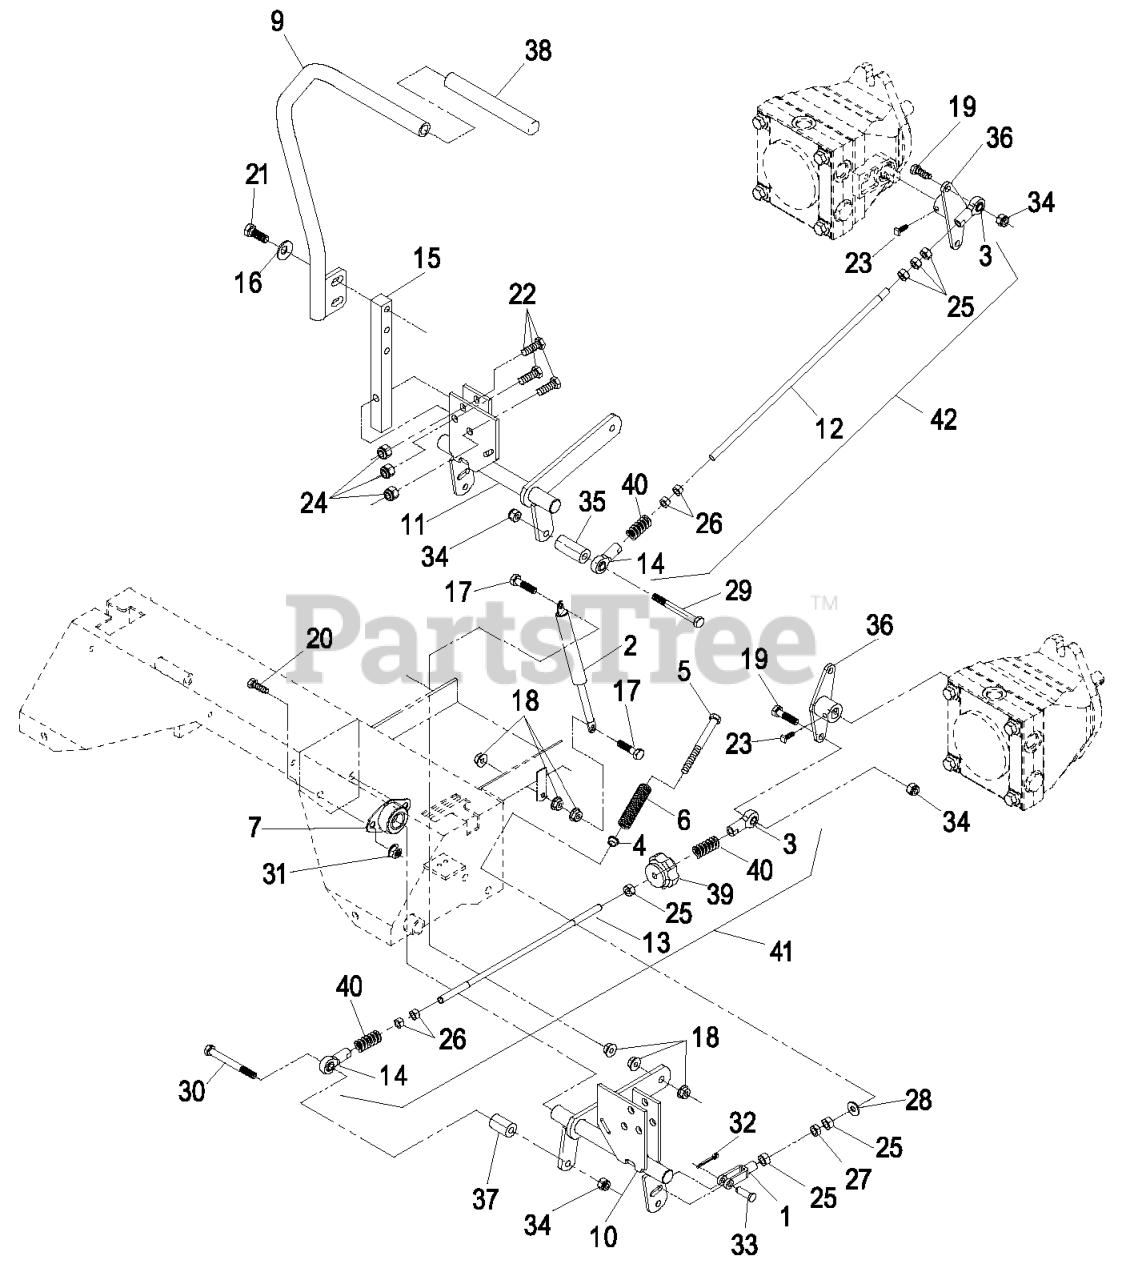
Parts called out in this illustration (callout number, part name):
1	YOKE-ADJUSTABLE
3	BALLJOINT-RH
4	BUSHING-FLANGED
5	BOLT-RETURN, NEUTRAL
6	SPRING-RETURN, NEUTRAL
7	BEARING-FLANGE, SIDE
9	ASM.RH LEVER/GRIP
12	LINK,XP HYDRO CONNECT RH
13	LINK,TRACKING ROD XP
14	BALLJOINT-LH
15	ARM-SHAFT, CONTROL
16	WASHER-BELLEVILLE
17	SCREW-HH
19	SCREW-HH
20	SCREW-HH
21	SCREW-HH
22	SCREW-HH
23	SCREW-SET
24	NUT-LOCK, NI
25	NUT-HEX
27	NUT-JAM
28	WASHER-FLAT
29	SCREW-HH
30	SCREW-HH
31	NUT-HHF, WHIZ
32	PIN-COTTER
33	PIN-CLEVIS
34	NUT-LOCK, NI
35	SPACER-CONTROL, HYD
36	ARM-CONTROL, HYDRO
37	SPACER-HYDRO CONTROL, LH
38	GRIP,CONTROL LEVER
39	KNOB-TRACKING
40	SPRING-COMPRESSION
41	TRACKING ROD ASM
42	RH HYD CONNECT LINK ASM
